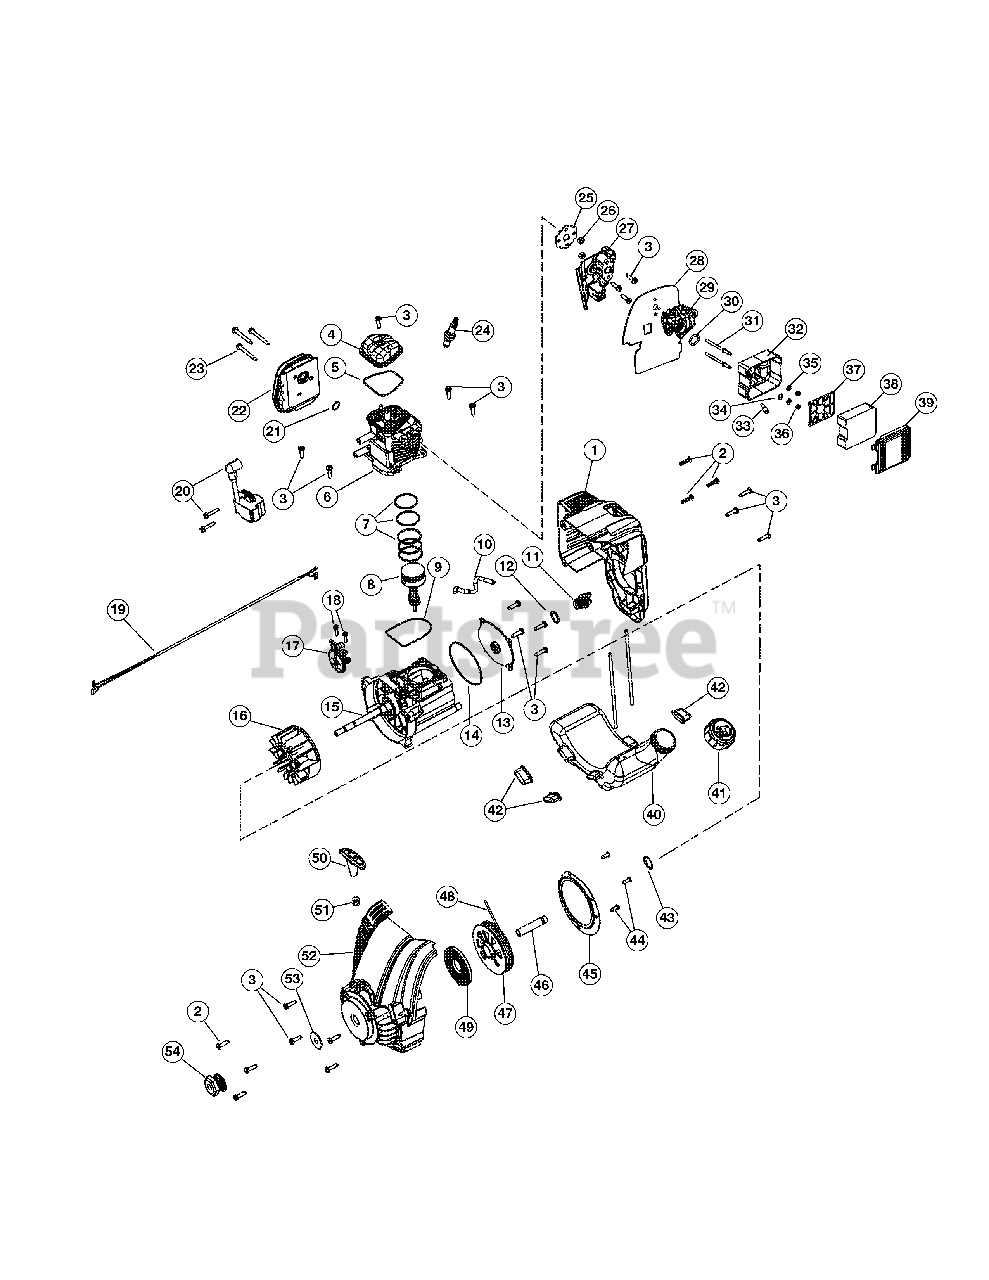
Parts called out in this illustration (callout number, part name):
1	Engine Cover Assembly
2	Cover Screw
3	Screw
4	Rocker Cover
5	Rocker Cover O-Ring
6	Cylinder Assembly
7	Piston Ring Assembly
8	Piston Assembly
9	Cylinder O-Ring
10	Breather Hose
11	Oil Plug
12	Oil Plug O-Ring
13	Crankcase Cover
14	Crankcase Cover O-ring
15	Crankcase Assembly
16	Flywheel Assembly
17	Cam Bracket Assembly
18	Cam Bracket Screw
19	Lead Wires
20	Module Assembly
21	Muffler Gasket
22	Muffler Assembly
23	Muffler Screw
24	Spark Plug
25	Insulator Gasket
26	Nut
27	Insulator
28	Carburetor Gasket
29	Carburetor w/Primer
31	Air Filter Mounting Screw
32	Air Cleaner Cover Assembly
33	Breather Tube
34	Grommet Washer
36	Nut
37	Air Filter Plate
38	Air Filter
39	Air Filter Cover
40	Fuel Tank Assembly w/Fuel Lines
42	Fuel Tank Pads
43	Push Nut
44	Pressure Plate Screw
45	Pressure Plate
46	Spacer
47	Starter Assembly
49	Recoil Spring
50	Handle
52	Starter Housing Assembly
53	Washer
54	Drive Shaft Pulley
